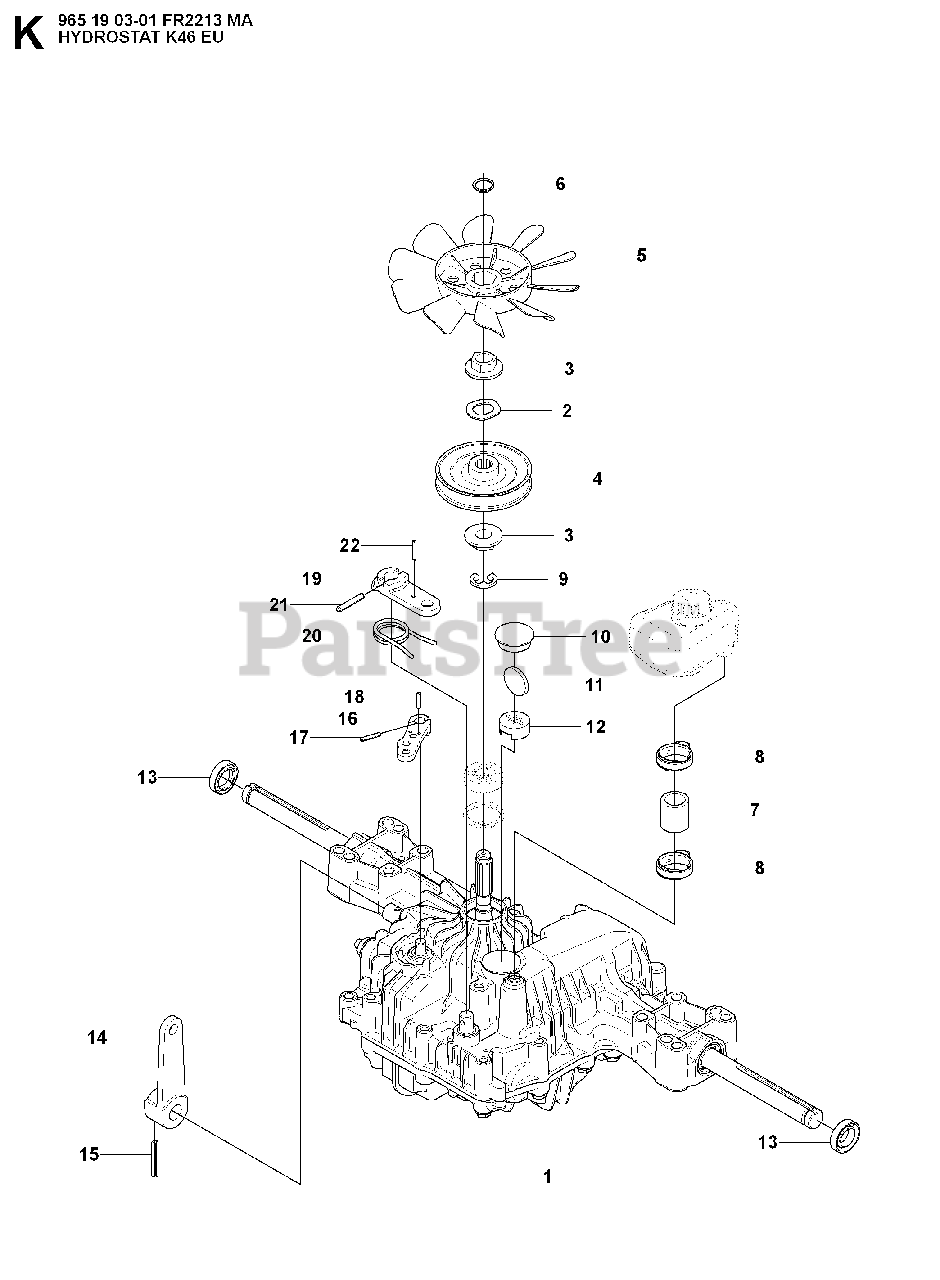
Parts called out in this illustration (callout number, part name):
1	HYDROSTAT
2	WASHER **
5	FAN
6	RETAINING RING **
8	CLAMP
12	MAGNET HOLDER
13	SEALING
14	CONTROL LEVER
20	RETURN SPRING
